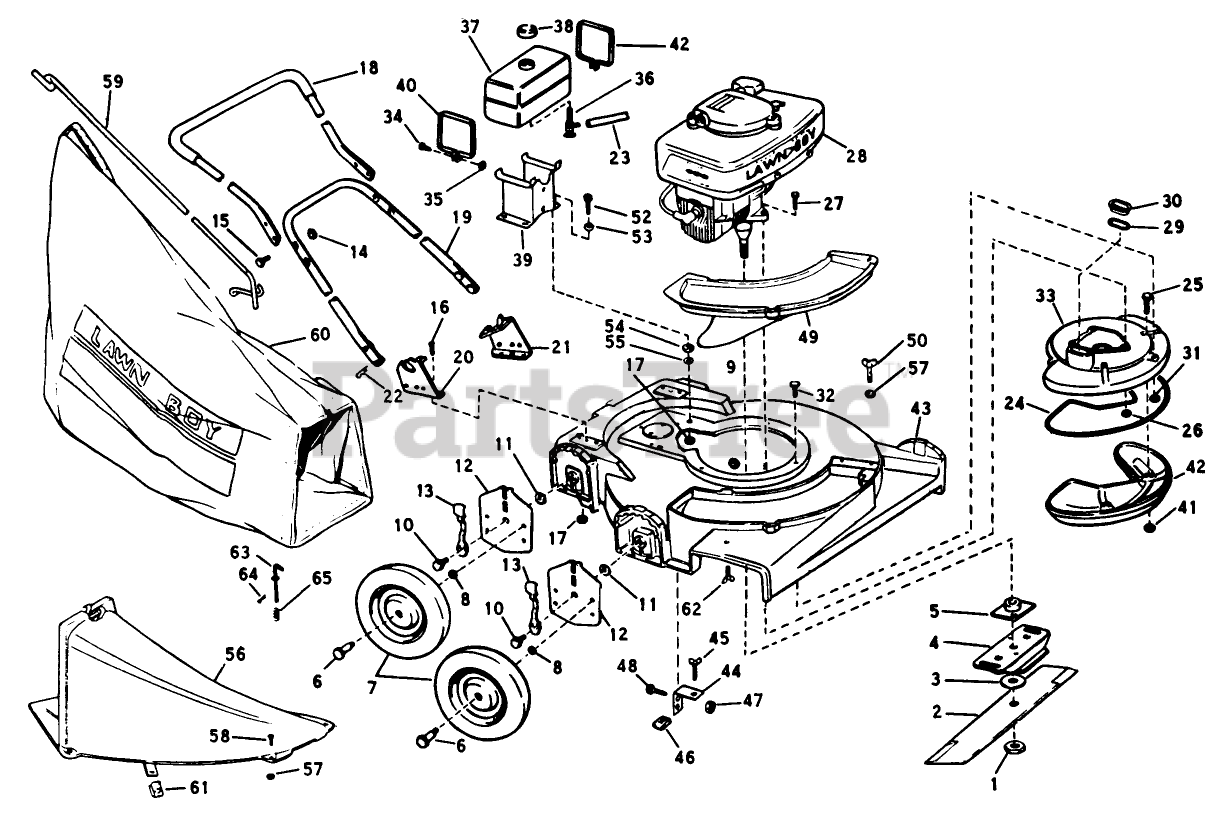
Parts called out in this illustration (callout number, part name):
1	NUT-BLADE
5	PLATE AND COLLAR ASM
6	BOLT-SHOULDER
8	WASHER M
9	WASHER WROUGHT
13	Spring-Wheel Adj.
14	STOP NUT
16	SCREW S
18	Handle Grip Assy. Top
29	GASKET S
36	VALVE&SCREEN SM
41	LOCKNUT E
46	SPEED NUT ARDEN
48	SCREW S
56	Chute and Spring Assy. (Includes Hardware)
60	89802 LB WHOLE GOODS
61	SPEED NUT ARDEN
